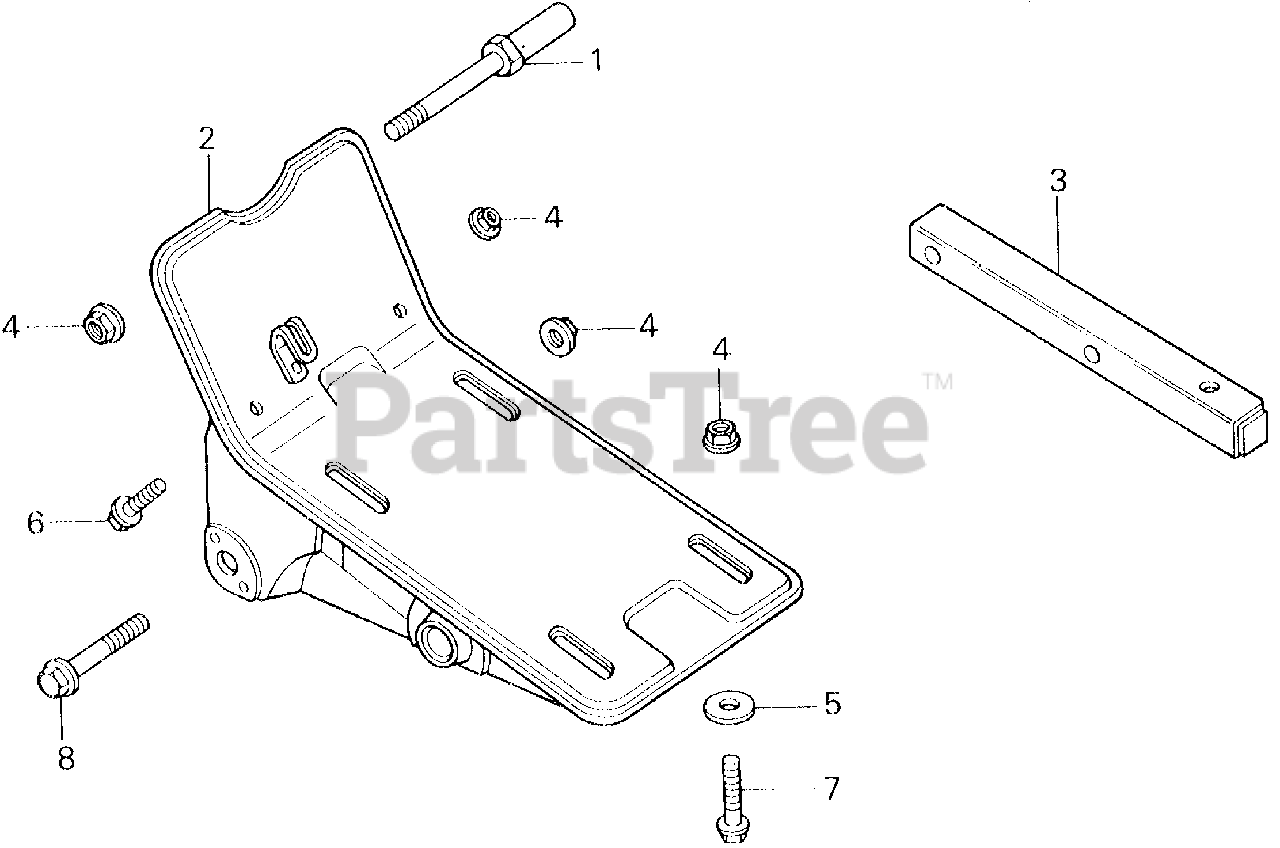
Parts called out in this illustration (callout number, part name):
1	BOLT, TENSIONER ARM
2	BED, ENGINE (NOT AVAILABLE)
3	BEAM, WEIGHT
4	NUT, FLANGE (8MM)
6	BOLT, FLANGE (8X16)
7	BOLT, FLANGE (8X32)
8	BOLT, FLANGE (8X45)
